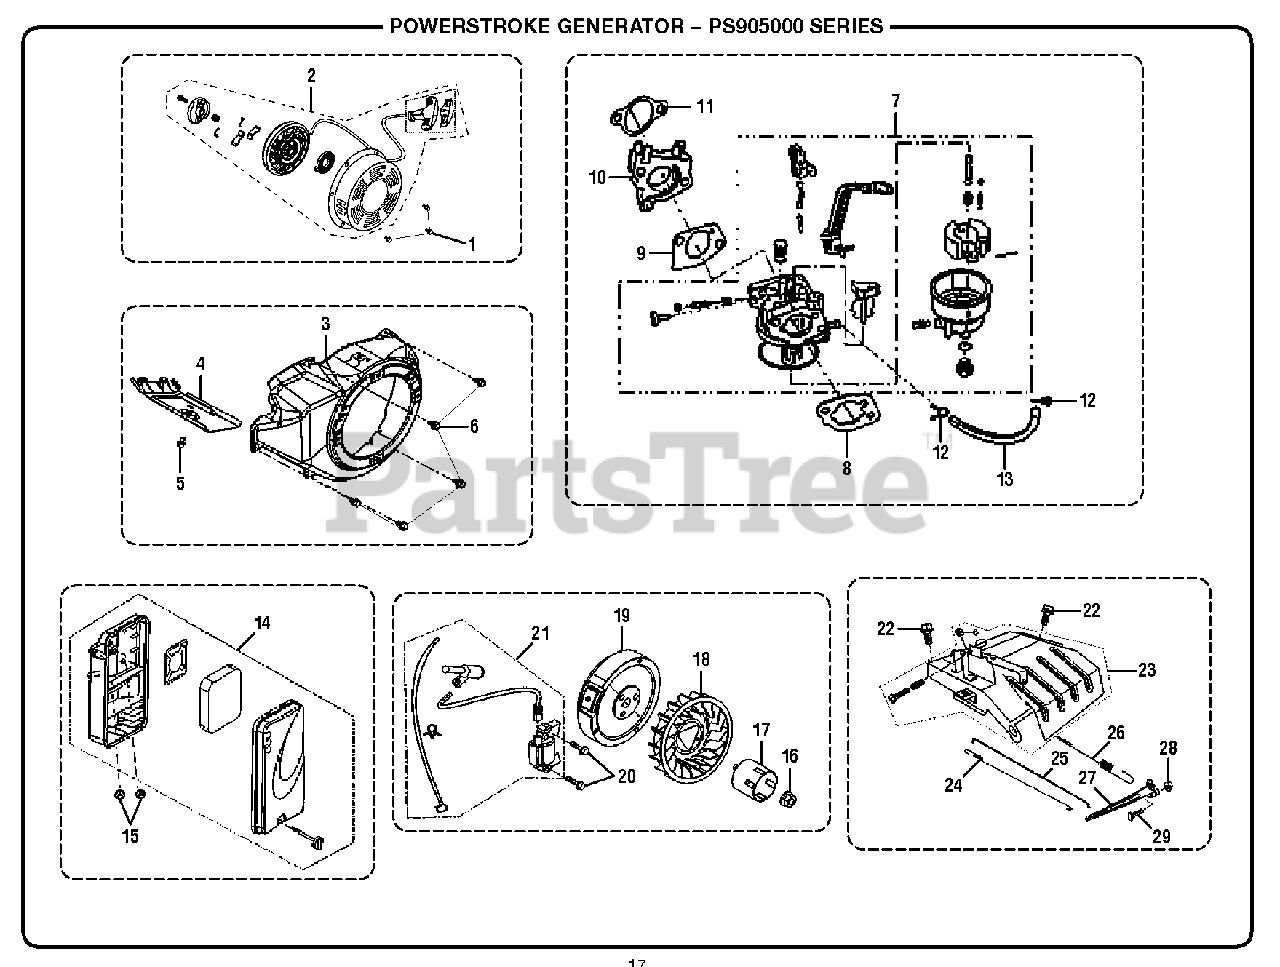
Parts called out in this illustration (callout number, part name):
2	Recoil Starter Assembly
4	Cylinder Body Shroud
7	Carburetor Assembly
8	Air Cleaner Gasket
9	Carburetor Gasket
10	Carburetor Insulator Plate
11	Inlet Gasket
14	Air Cleaner Assembly
16	Flywheel Nut
17	Starter Pulley
19	Flywheel Assembly
21	Ignition Coil
23	Throttle Control Assemby
24	Throttle Valve Return Spring
25	Governor Rod
26	Governor Spring
27	Governor Support Assembly
29	Bolt
